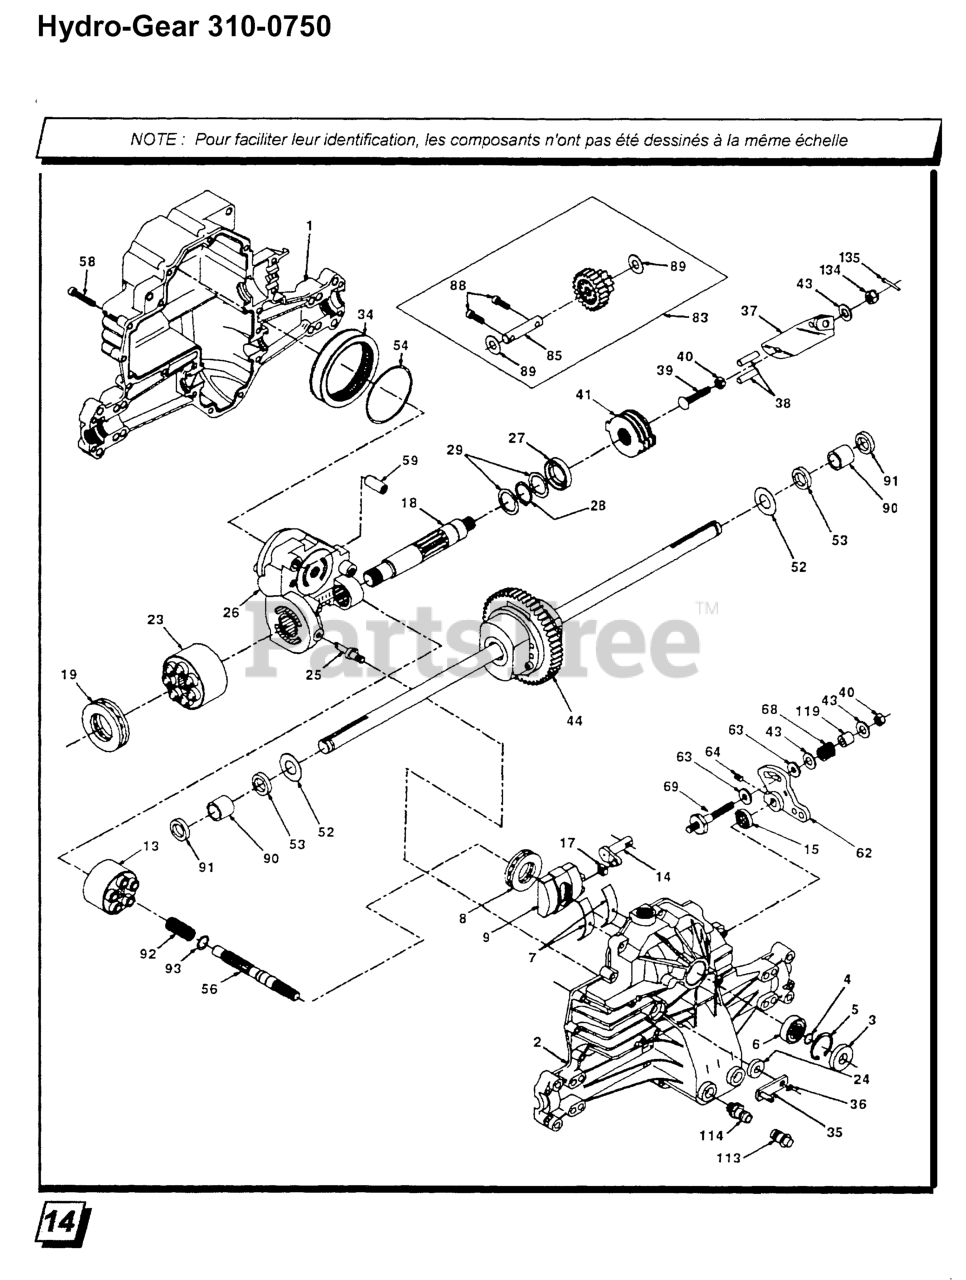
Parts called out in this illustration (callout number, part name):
1	LOWER HOUSING
2	HOUSING UPPER 70255
3	SEAL.LIP.H-G.(9008000-0128)
4	RING RETAINING 2003016
5	RING.RETAINING.(2003052)
6	BALL BEARING
7	CRADLE BEARING
8	THRUST BEARING
9	SWASHPLATE (2003087)
13	BLOCK, CYL ASSY
14	TRUNNION ARM
17	SLOT GUIDE
18	MOTOR SHAFT
19	THRUST BEARING
23	BLOCK, CYL ASSY
25	BYPASS ACTUATOR
26	CENTER SECTION ASSY KIT
28	RETAINING RING
34	ELEMENT, OIL FILTER
35	BYPASS ARM
36	RETAINING RING 44870
37	ACTUATING ARM
38	ACTUATING PIN 44891
40	NUT.LOCK.HX.(H-G PART 50108)
41	BRAKE ROTOR 70135 HYDRO-GEAR
43	WASHER .34X.88X.06.44130
44	KIT SVC DIFF 70130
52	WASHER.HYDRO GEAR.50152
53	SEAL.HYDRO.53901
56	SHAFT.INPUT.50005
58	BOLT #44876
62	CONTROL ARM 50254
63	DAMPENER PUCK
64	SCREW.SET.50018
68	SPRING HELICAL COMP 50277
69	SCREW
83	JACK SHAFT ASSY
85	JACK SHAFT
89	WASHER 50132
90	SLEEVE.BEARING 50118
91	RP SEAL, WIPER
92	SPRING 2003014
113	CAP, VENT ASSY
114	O-RING KIT 70110
119	SPACER.HYDRO GEAR 50278
134	NUT.CAS.HYD.44142
135	ID DOT HYDD
